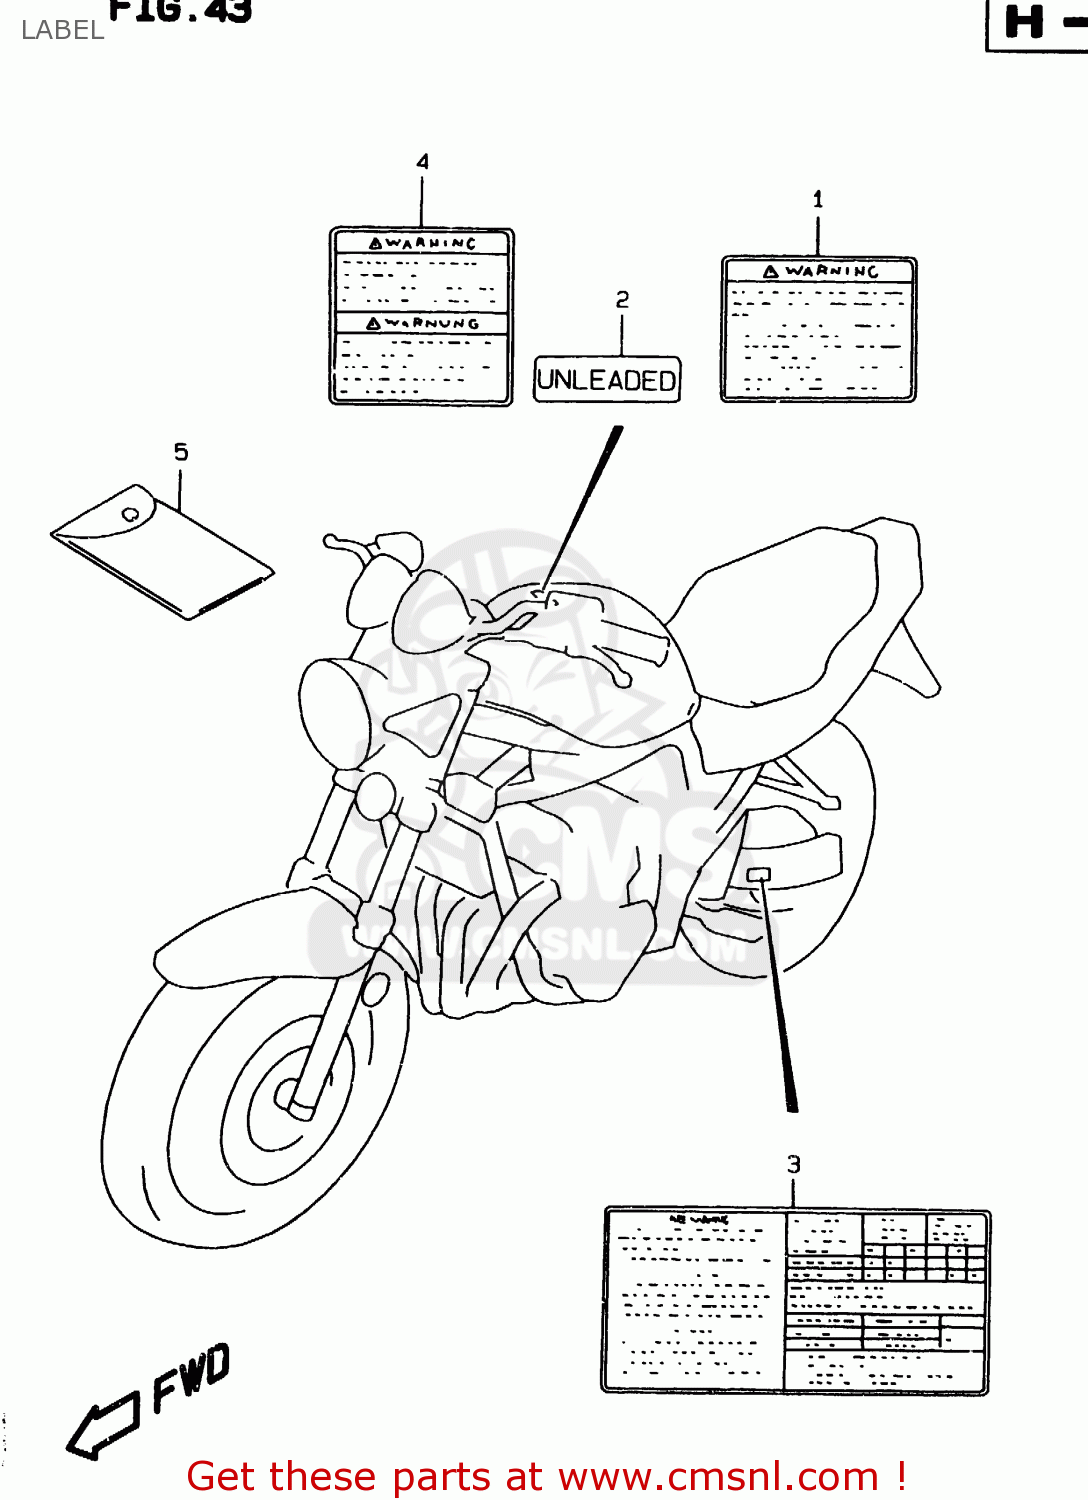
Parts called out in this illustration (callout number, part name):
1	LABEL,WARNING
2	LABEL,CAUTION
3	LABEL,TIRE PRS
4	LABEL,WARNING STEERING
5	BAG COMP,OWNERS MANUAL
6	O.M. GSF1200S
7	MANUAL, SUPPLEMENT
